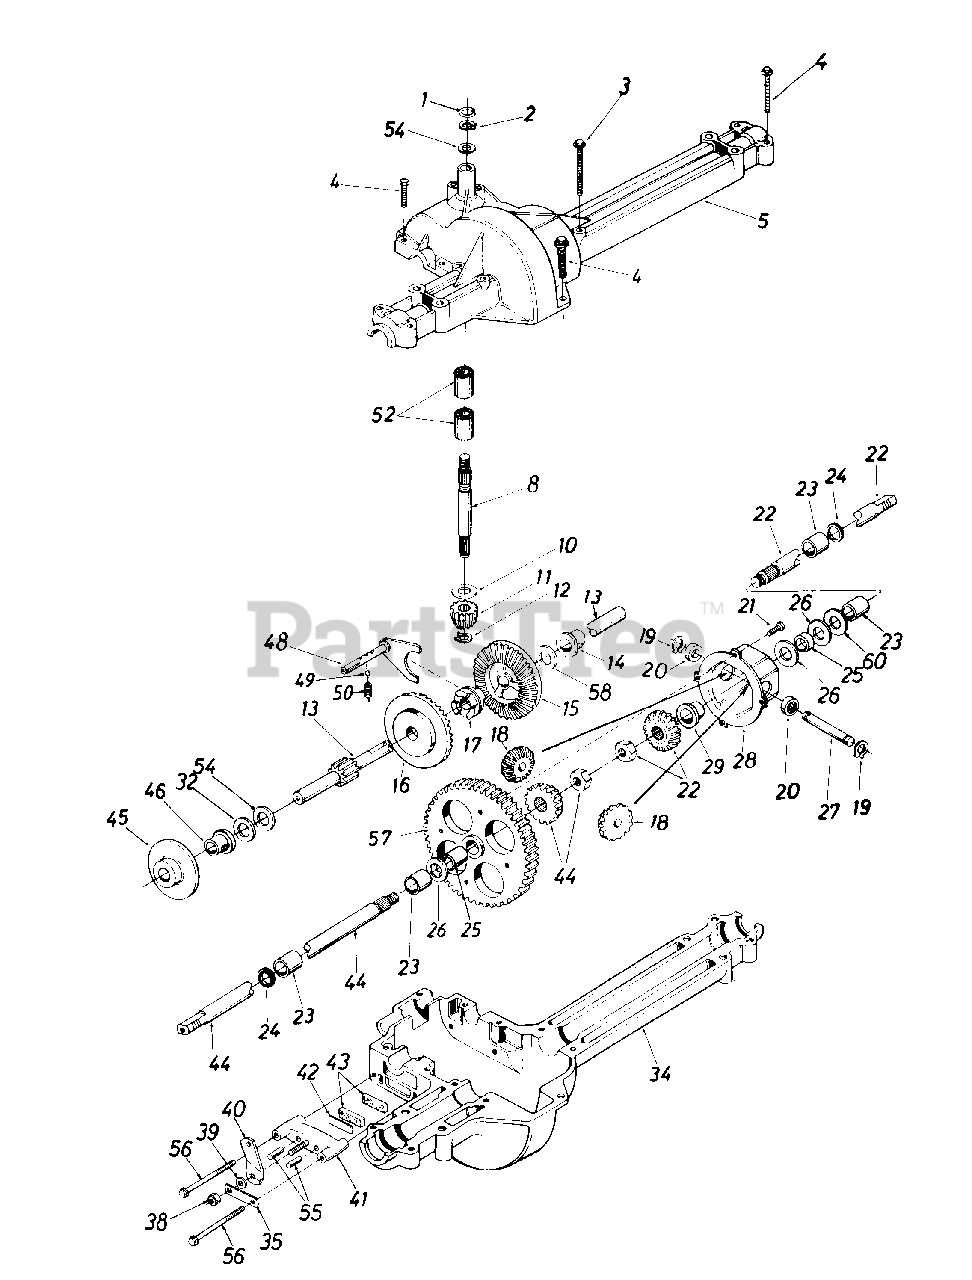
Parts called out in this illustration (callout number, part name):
1	Wire Ring
2	Retaining Ring
3	Hex Bolt 1/4-20 x 1.75" Lg.
4	Hex Tap Scr. 1/4-20 x 1.25" Lg.
5	Upper Housing
8	Input Shaft
10	Thrust Washer 5/8" I.D. x 1.25" O.D.
11	Pinion Input 14T
12	Retaining Ring
13	Drive Shaft--L.H. Brake
14	Flange Brg. 5/8" I.D. x 3/4"
15	Bevel Gear 42T--Small l.D.
16	Bevel Gear 42T--Large l.D.
17	Clutch Collar
18	Miter Gear 15T (H.D.)
19	Snap Ring
20	Thrust Bearing
21	Pan Head Scr. 1/4-20 x .50" Lg. w/Patch
22	Axle R.H. Ass'y.
23	Sleeve Bearing 3/4" I.D. x 1.0" Lg.
24	Oil Seal 3/4" I.D.
25	Axle Spacer
26	Fl-Wash. .760" I.D. x 1.5" O.D. x .6" Thk.
27	Cross Shaft
28	Differential Can Ass'y.
32	Thrust Wash. 5/8" I.D. x 1" O.D. x .025" Thk.
34	Lower Housing
35	Anti-Rotation Brkt.
38	Hex Nut 5/16-24 Thd.
39	Fl-Wash. .344" I.D. x .875" O.D.
40	Actuating Arm
41	Brake Yoke
42	Puck Plate
43	Brake Puck
44	Axle L.H. Assy.
45	Brake Disc
46	Flange Bearing 5/8" I.D. x 15/16" Lg.
48	Shift Fork Ass'y.--1/2" Dia.
49	Ball Detent .250" Dia.
50	Spring Detent
52	Needle Brg. 5/8" I.D. x 1/2" Lg.
54	Fl-Wash. 5/8" I.D. x 1" O.D. x .020 Thk.
55	Actuating Pin 5/16" Dia.
56	Hex Wash Hd. Self-Tap Scr. 1/4-20 Thd.
57	Differential Gear 58T
58	Fl-Wash. 5/8" I.D. x 1" O.D. x .020 Thk.
60	Fl-Wash. .76" I.D. x 1.5" O.D. x .010" Thk.
